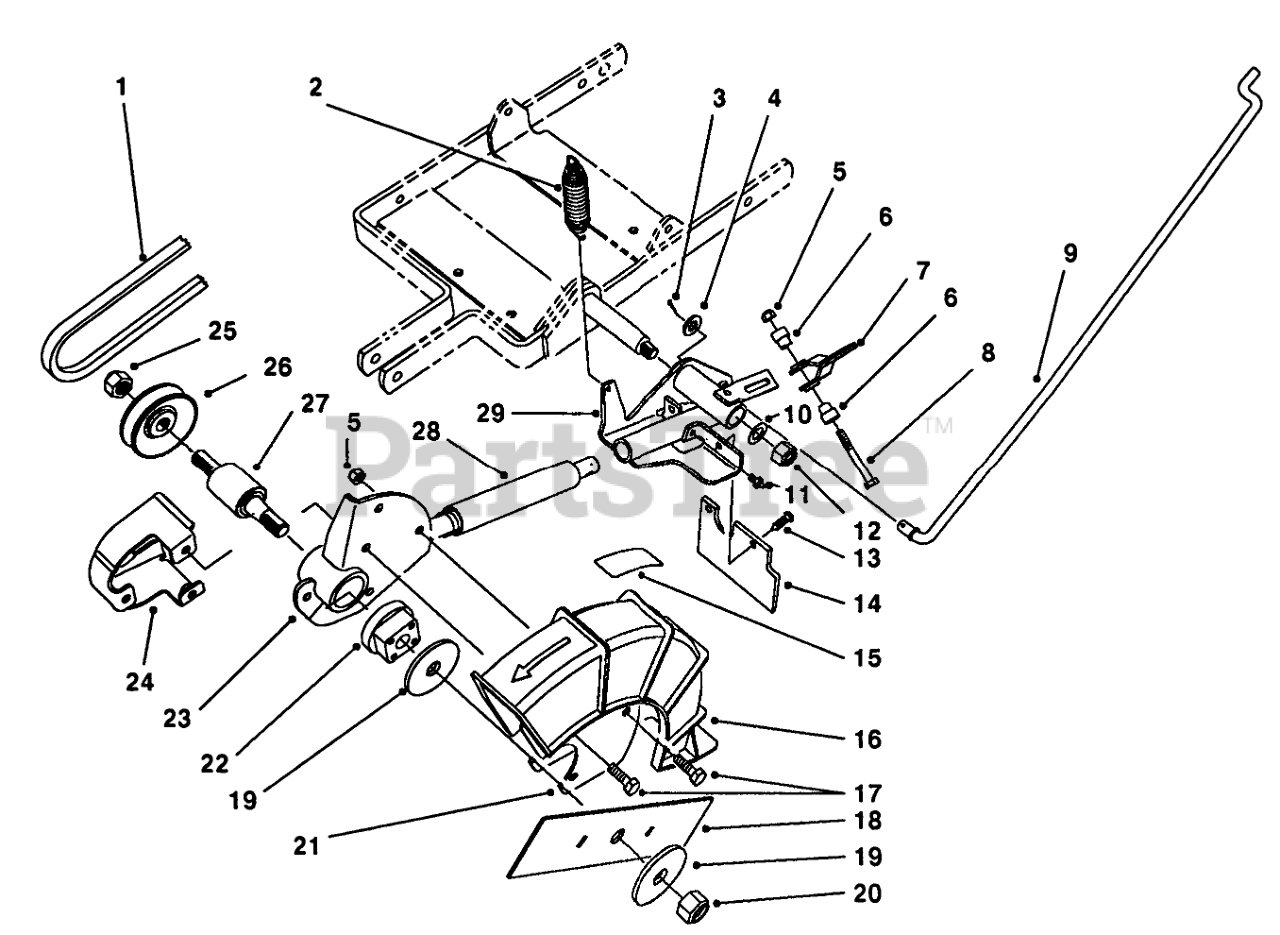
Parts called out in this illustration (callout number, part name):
1	V-BELT
2	EXT. SPRING
3	PIN-COTTER
4	WASHER-FLAT
5	NUT-LOCK, NI
6	SPACER-PIVOT LEVER
7	LEVER WA
8	SCREW-HH
9	LOWER CONTROL ROD
10	WASHER-PLAIN
11	FITTING-GREASE
12	NUT-LOCK, NI
13	PANEL FASTENER
14	RUBBER GUARD
15	Decal-Warning
16	Blade Guard Assy. (Incl. Ref. #15)
17	SCREW-HWHTF
18	9" EDGER BLADE
19	WASHER-LARGE
20	NUT-HEX
21	GUARD PLATE
22	BRG SHIELD
23	HUB ASM
24	PULLEY GUARD WA
25	NUT-LOCK, NI
26	PULLEY
27	SPINDLE ASM
28	SPRING & BELLOW ASM
29	PIVOT ARM WA
